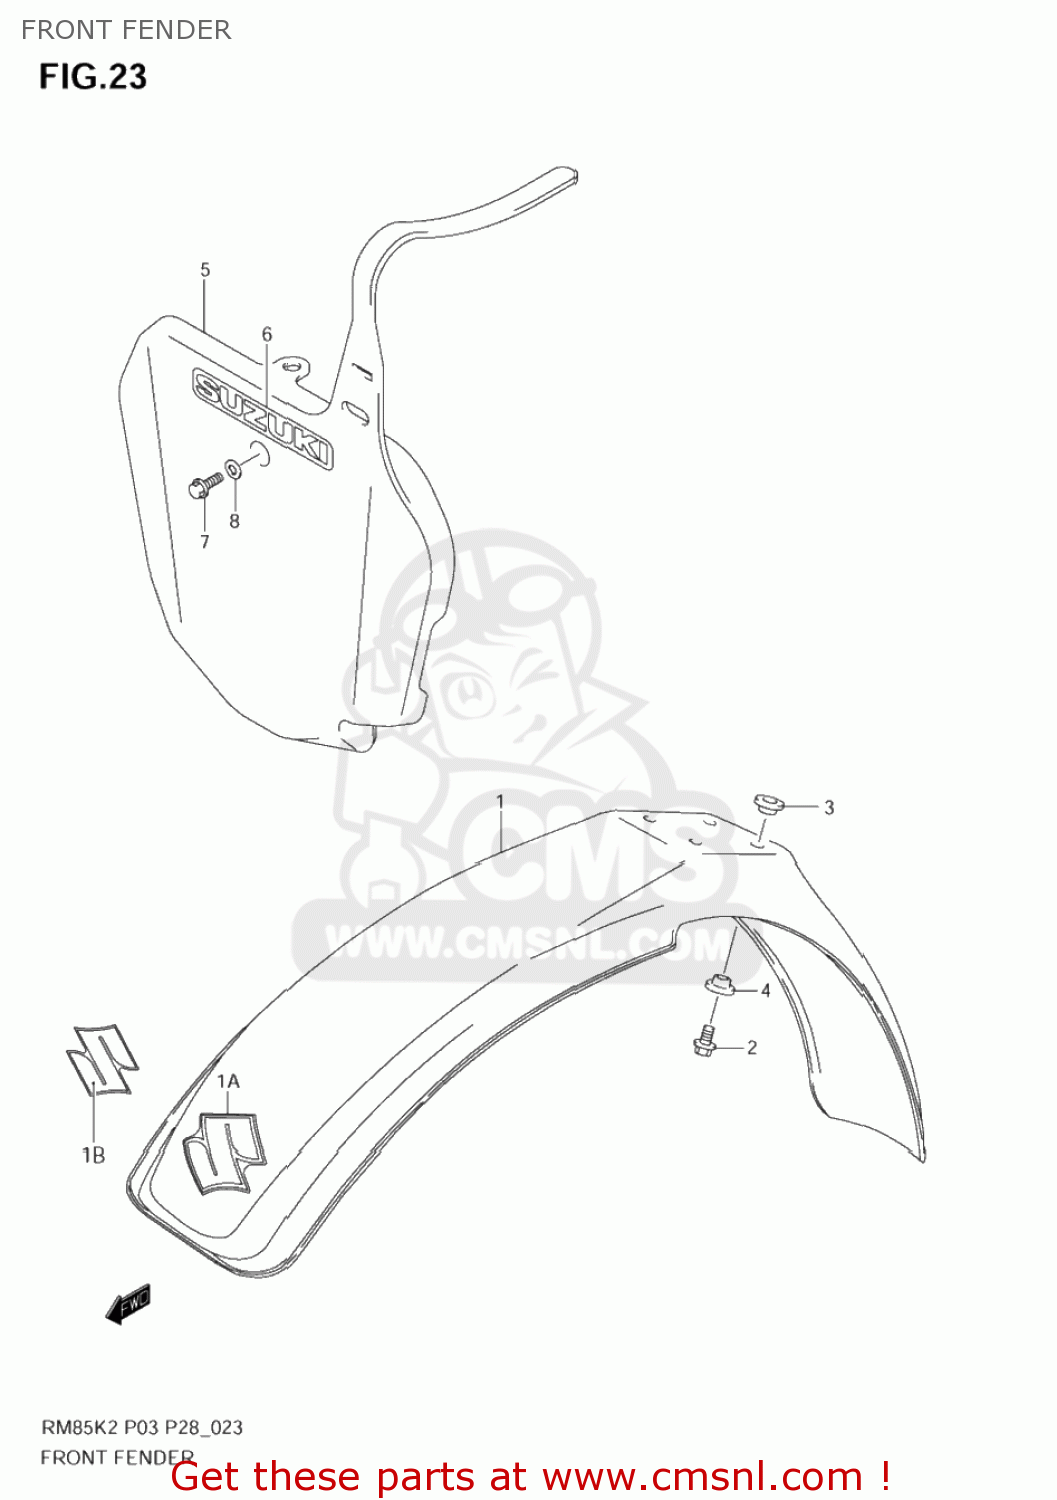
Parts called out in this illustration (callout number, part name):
1	FENDER,FR
1A	EMBLEM,S
1B	EMBLEM,S
2	BOLT,6X20
3	WASHER
4	WASHER
5	PLATE,NUMBER FR
6	EMBLEM,SUZUKI
7	BOLT,6X20
8	WASHER
